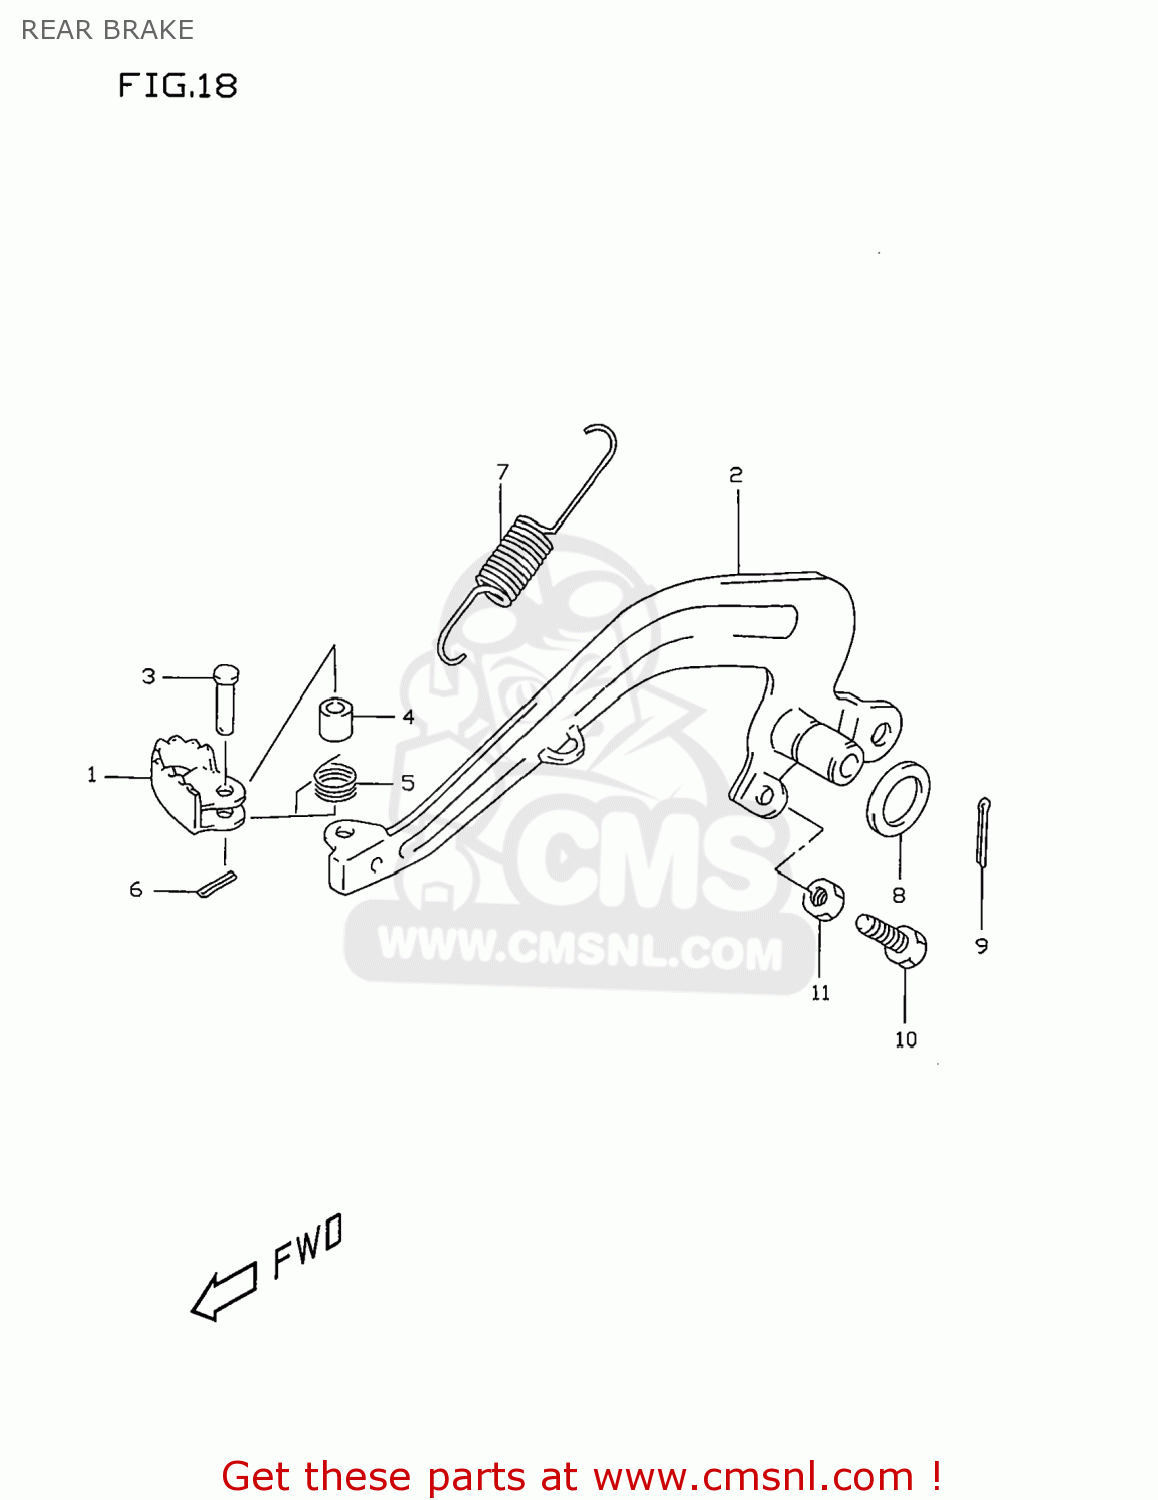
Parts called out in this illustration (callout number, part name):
1	PEDAL,BRAKE
2	ARM,BRAKE PEDAL
3	PIN
4	SPACER(6.5X9X6.5)
5	SPRING
6	PIN
7	SPRING
8	WASHER(15.5X26X2.3)
9	PIN, COTTER
10	SCREW(6X23)
11	NUT 6MM
